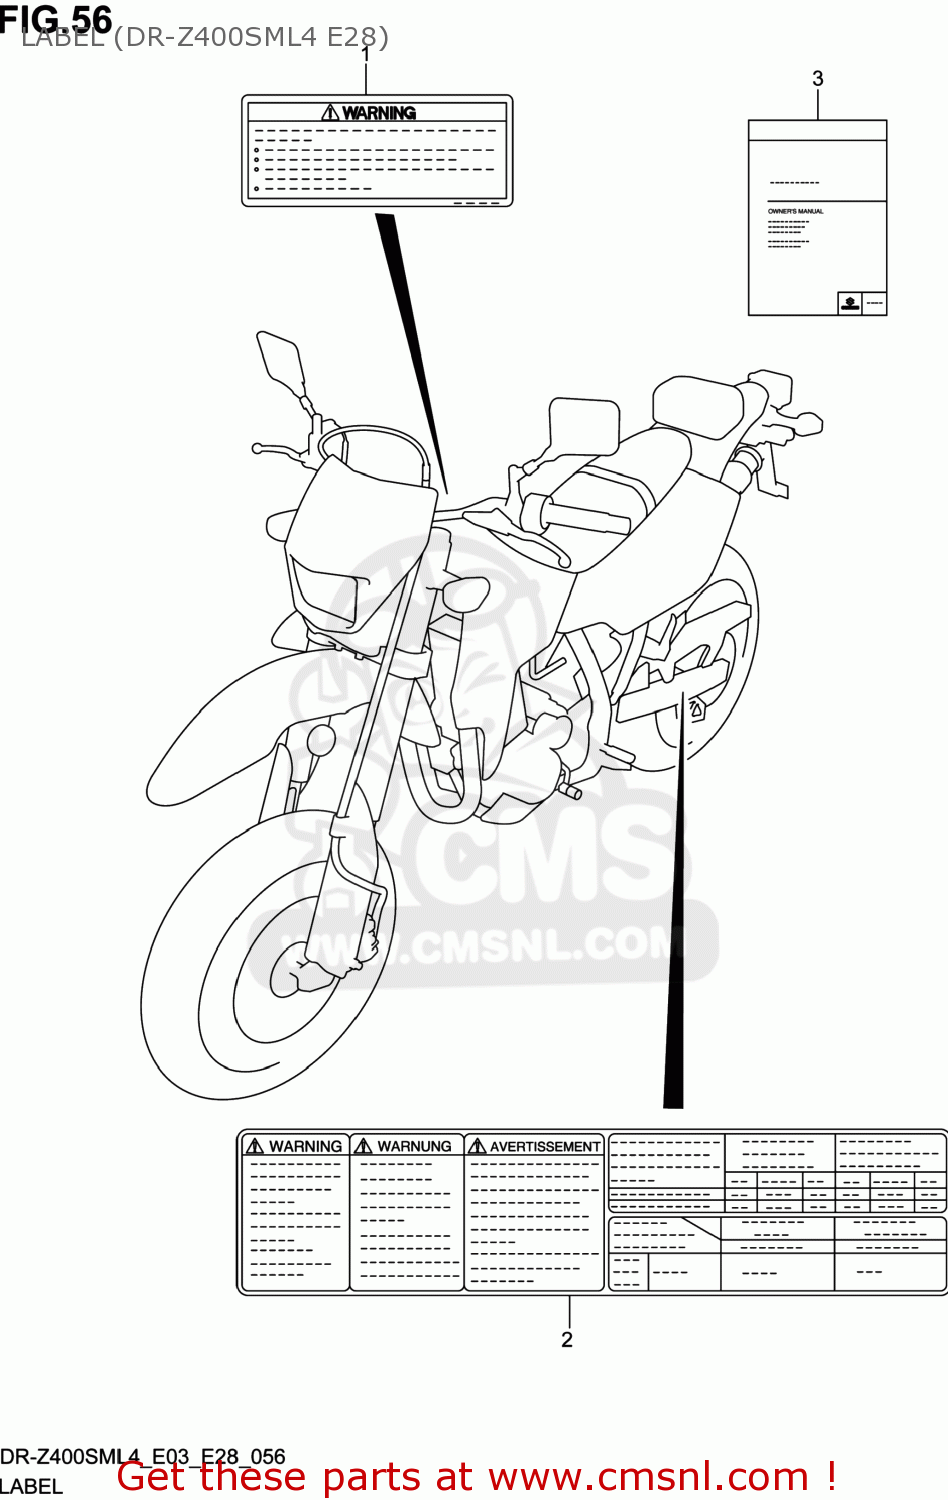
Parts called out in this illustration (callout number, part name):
1	LABEL,GENERAL WARNING
2	LABEL,TIRE INFORMATION
3	MANUAL,OWNER'S
